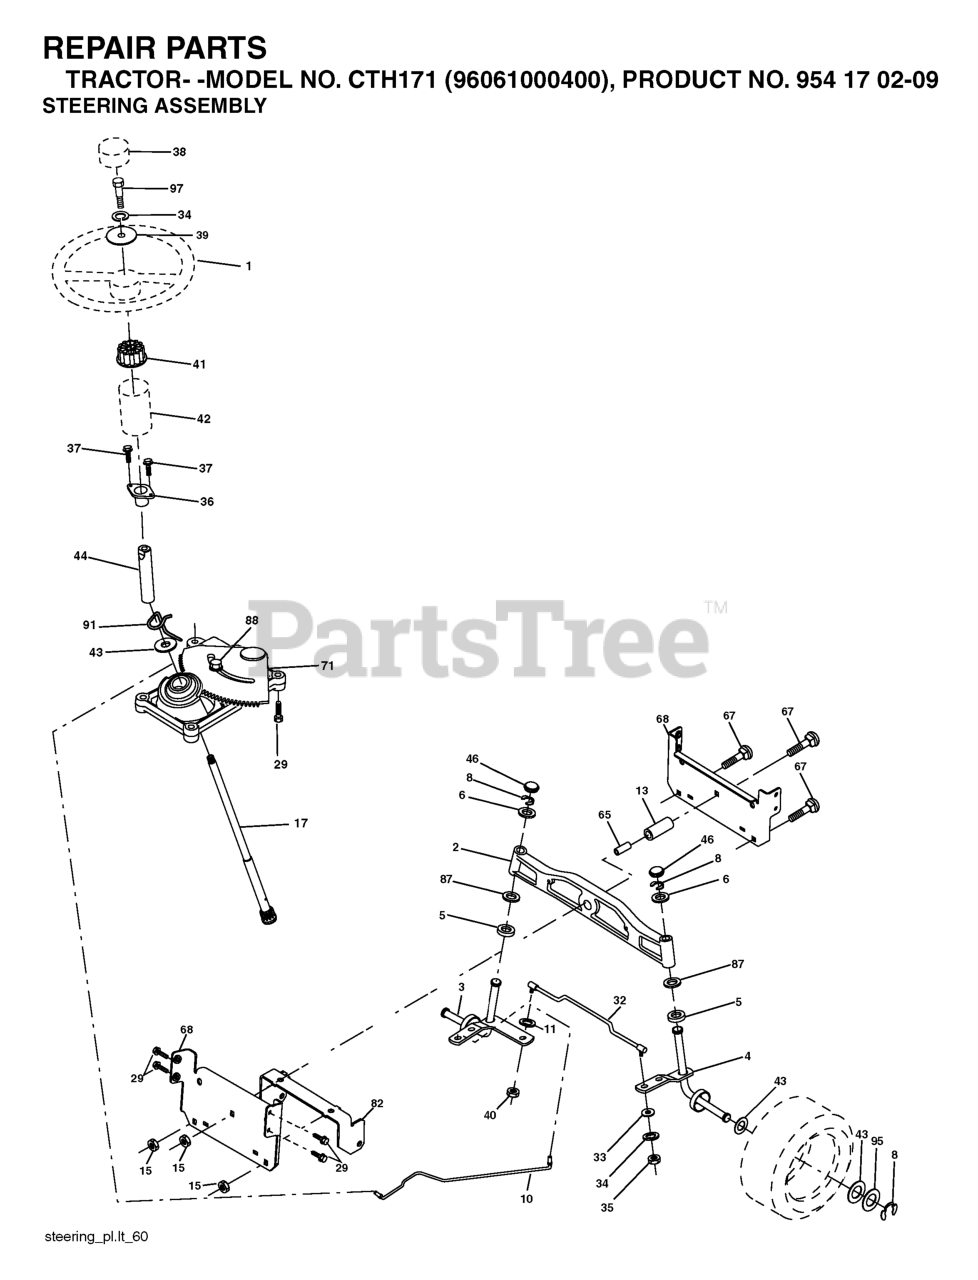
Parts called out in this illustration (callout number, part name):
1	STEERING WHEEL
2	AXLE ASSY FRONT
3	SPINDLE.ASM.LH.15"TIRES
4	SPINDLE.ASM.RH.15"TIRES
5	THRUST WASHER
10	DRAGLINK.15".TIRES.2001
11	WASHER, LOCK 3/8
12	NUT.HEX.1/2-20
13	TUBE, PIVOT AXLE
15	NUT
17	SHAFT STEERING SPLINE
29	SCREW, 3/8-16X3/4
32	ROD.ASM.TIE.BALL.JOINT.NOVAN
33	WASHER M
34	WASHER.LOCK.HVY.HLCL.SPR.5/16
35	NUT, CROWNLOCK
36	BUSHING, STEERING
37	SCREW.TT.#10-32X.5.3/8.FLANGE
38	INSERT.CAP.STRG.WH.GRAY
39	WASHER.11/32
40	NUT CROWNLOCK 3/8-24
41	ADAPTER, WHEEL STNG..
42	BOOT STEERING
44	SHAFT.EXTEN.STRG.SPLINE
46	CAP.SPINDLE.BLACK
65	SPACER BRACE AXLE
67	BOLT CARRIAGE
68	BRACE.AXLE.15"TIRES
71	STEERING ASM
82	BRACKET
87	WASHER, FLAT .781 X 1 1/2"
88	BOLT, SHOULDER 7/16-20
91	CLIP.STEERING
95	WASHER.HARDENED
